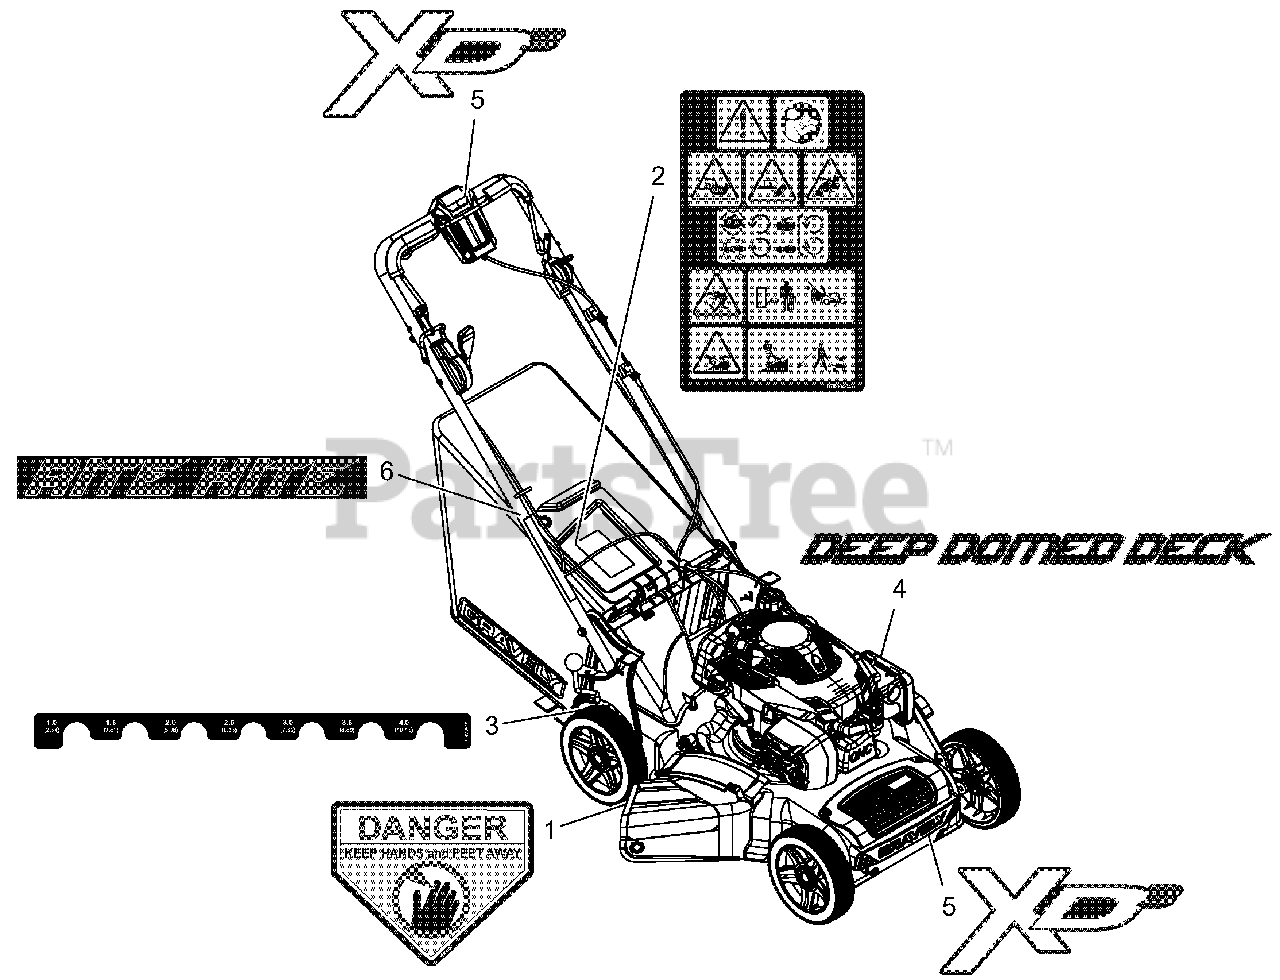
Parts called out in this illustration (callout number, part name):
1	DECAL, DANGER
2	DECAL, MAIN SAFETY WAW LM
3	DECAL, HOC
4	DECAL, DEEP DOME DECK
5	DECAL, GRAVELY XD3 STYLE
6	DECAL, RITE HITE
